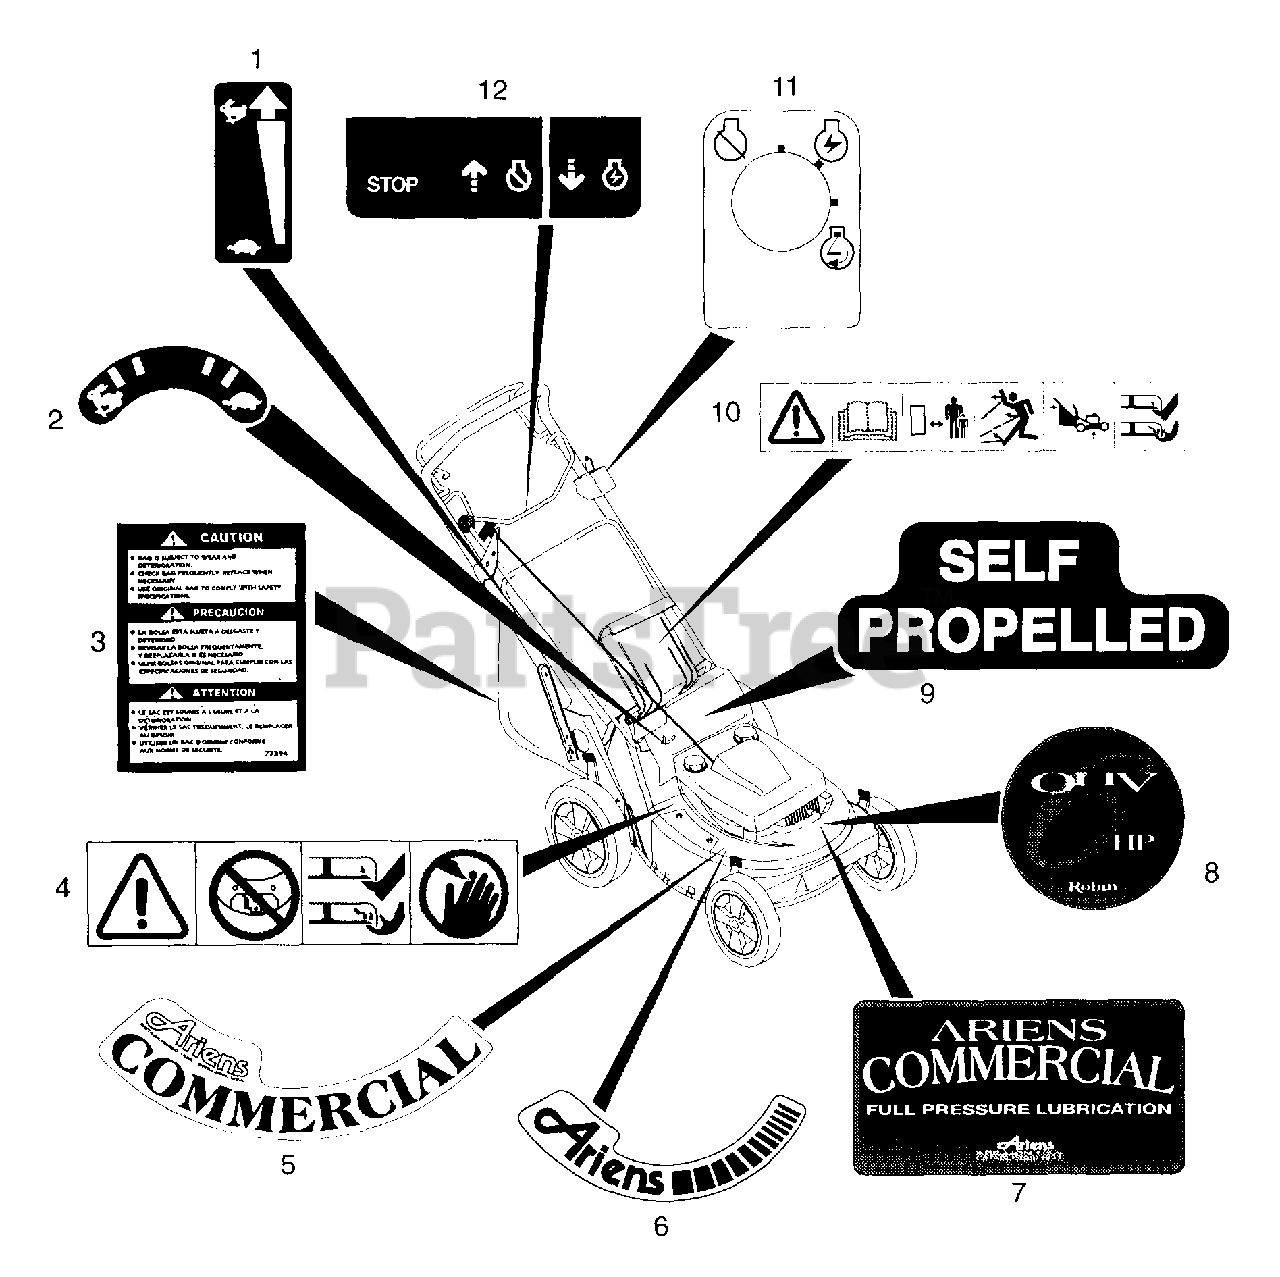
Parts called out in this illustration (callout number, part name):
1	DECAL-SPEED CONTROL
2	DECAL-SPEED SELECTOR
3	LABEL - BAGGER 21"
4	DECAL, DANGER
5	DECAL - COMMERCIAL
6	DECAL, ARIENS
7	DECAL ROBIN COMMERCIAL
8	DECAL 6HP
9	DECAL SELF PROPELLED
10	DECAL, BILINGUAL DANGER
11	DECAL-KEY SWITCH
12	DECAL - ENGINE CONTROL
